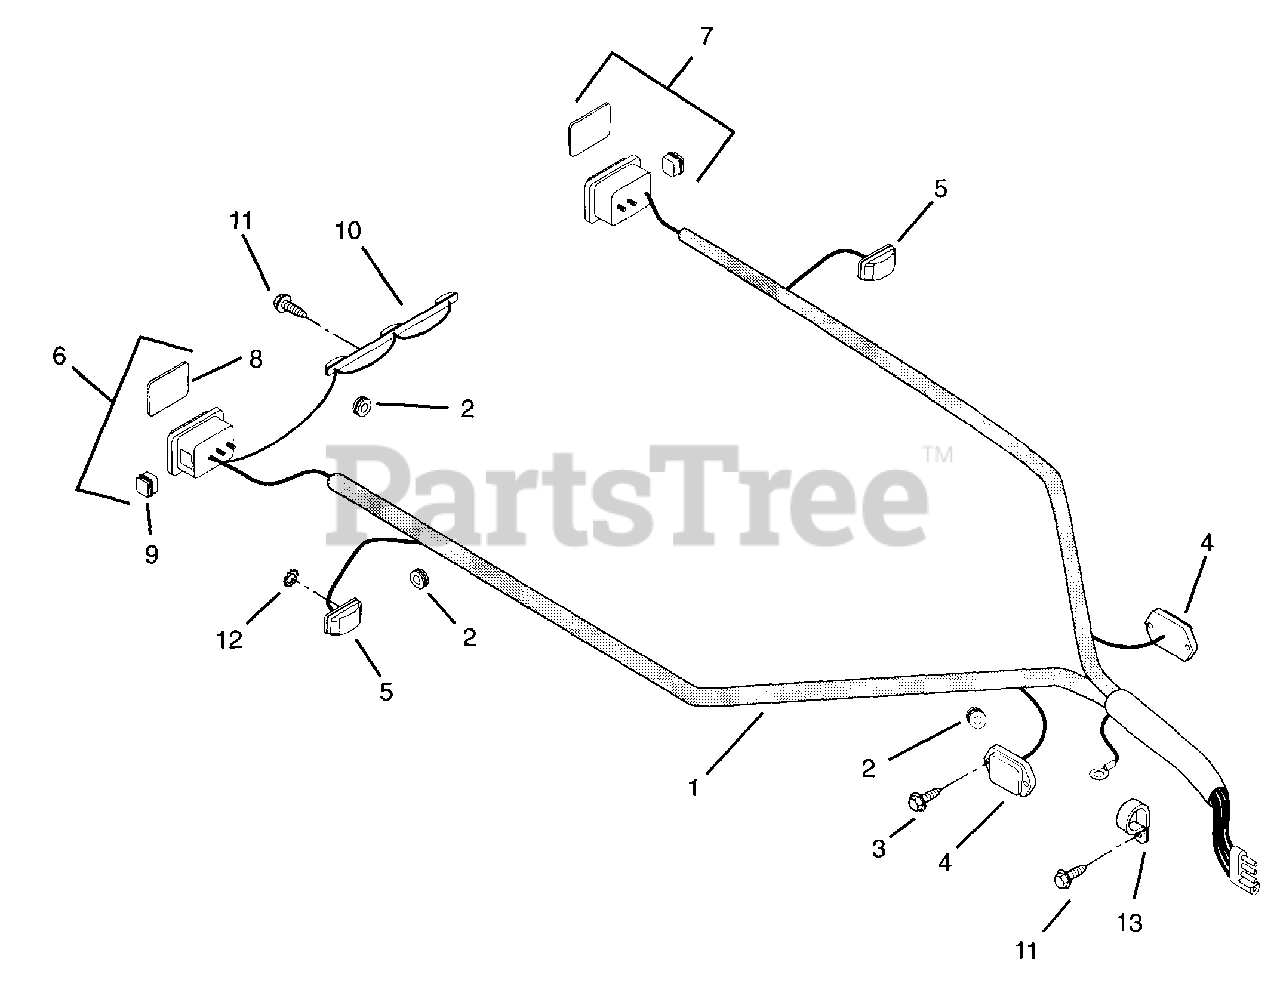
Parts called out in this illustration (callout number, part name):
1	Wiring Harness-Trailer Lights
2	Grommet .188 x .500 Inside Diameter
3	Screw-Tapping 10-24 x .50 Hex Washer Head
4	Light-Side Marker-Ear Mount
5	Light-Amber-Stud Mount
6	Tail Light-Right Hand
7	Tail Light-Left Hand
8	Lens-Tail Light Replacement
9	Lens-S/M Replacement
10	Light Bar-ID Bar
11	Screw-Tapping-Hex Washer Head .25 x .50
12	Washer-Locking-External .262 x .502 x .026
